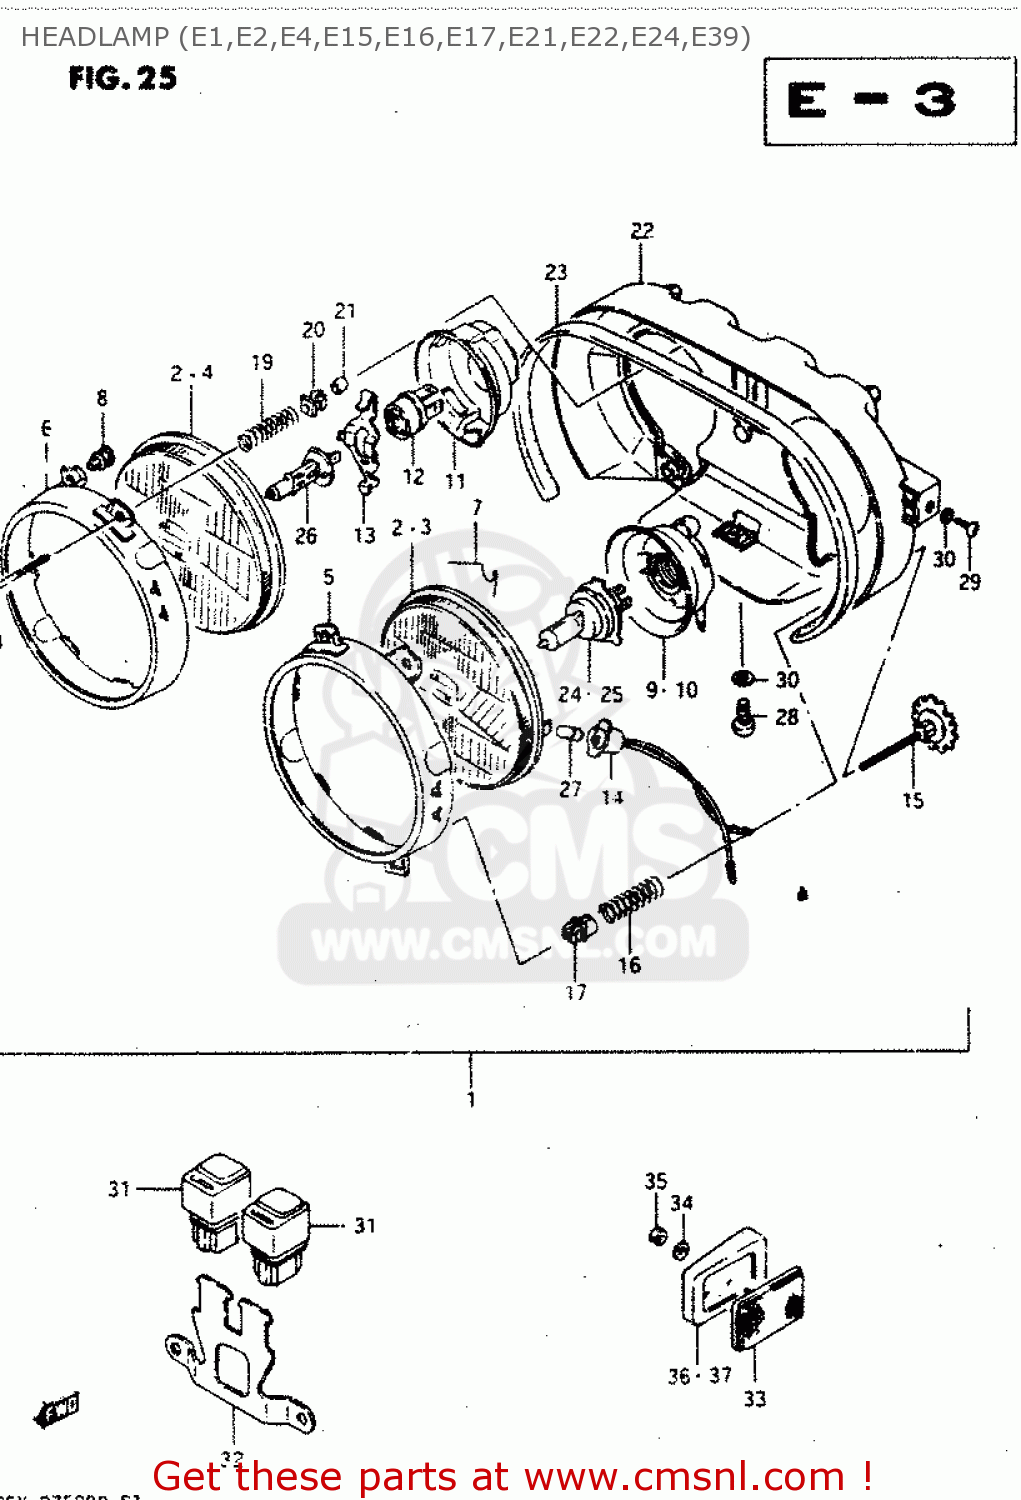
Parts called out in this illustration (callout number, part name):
1	HEADLAMP ASSY
2	UNIT
3	LAMP UNIT,L
4	UNIT, RH
5	RING, RETAINING LH
6	RING,RETAINING,RIGHT
7	SPRING, SUPPORT
8	SCREW,SPHERICAL
9	COVER,SOCKET
10	COVER,SOCKET
11	COVER, SOCKET,LH
12	ADAPTER
13	SPRING,PLATE
14	SOCKET
15	SCREW,ADJUSTER
16	SPRING
17	NUT
18	SCREW,ADJUSTER
19	SPRING
20	NUT
21	CAP,SCREW
22	HOUSING,HEADLAMP
23	GASKET (NAS)
24	BULB(12V60/55W,H4)
25	BULB(12V60/55W,H4)
26	BULB(12V55W/H1/P14.5S/OSRA,PHI
27	BULB(12V4W)
28	SCREW
29	SCREW
30	WASHER,LOCK
31	RELAY, ANTINOSE DIVE FORK
32	BRACKET,HEADLAMP RELAY
33	REFLEX REFLECTOR, FRONT SIDE
34	WASHER,5MM
35	NUT ,5MM
36	SPACER,FRONT SIDE,REAR,RIGHT
37	SPACER,FRONT SIDE,REAR,LEFT
